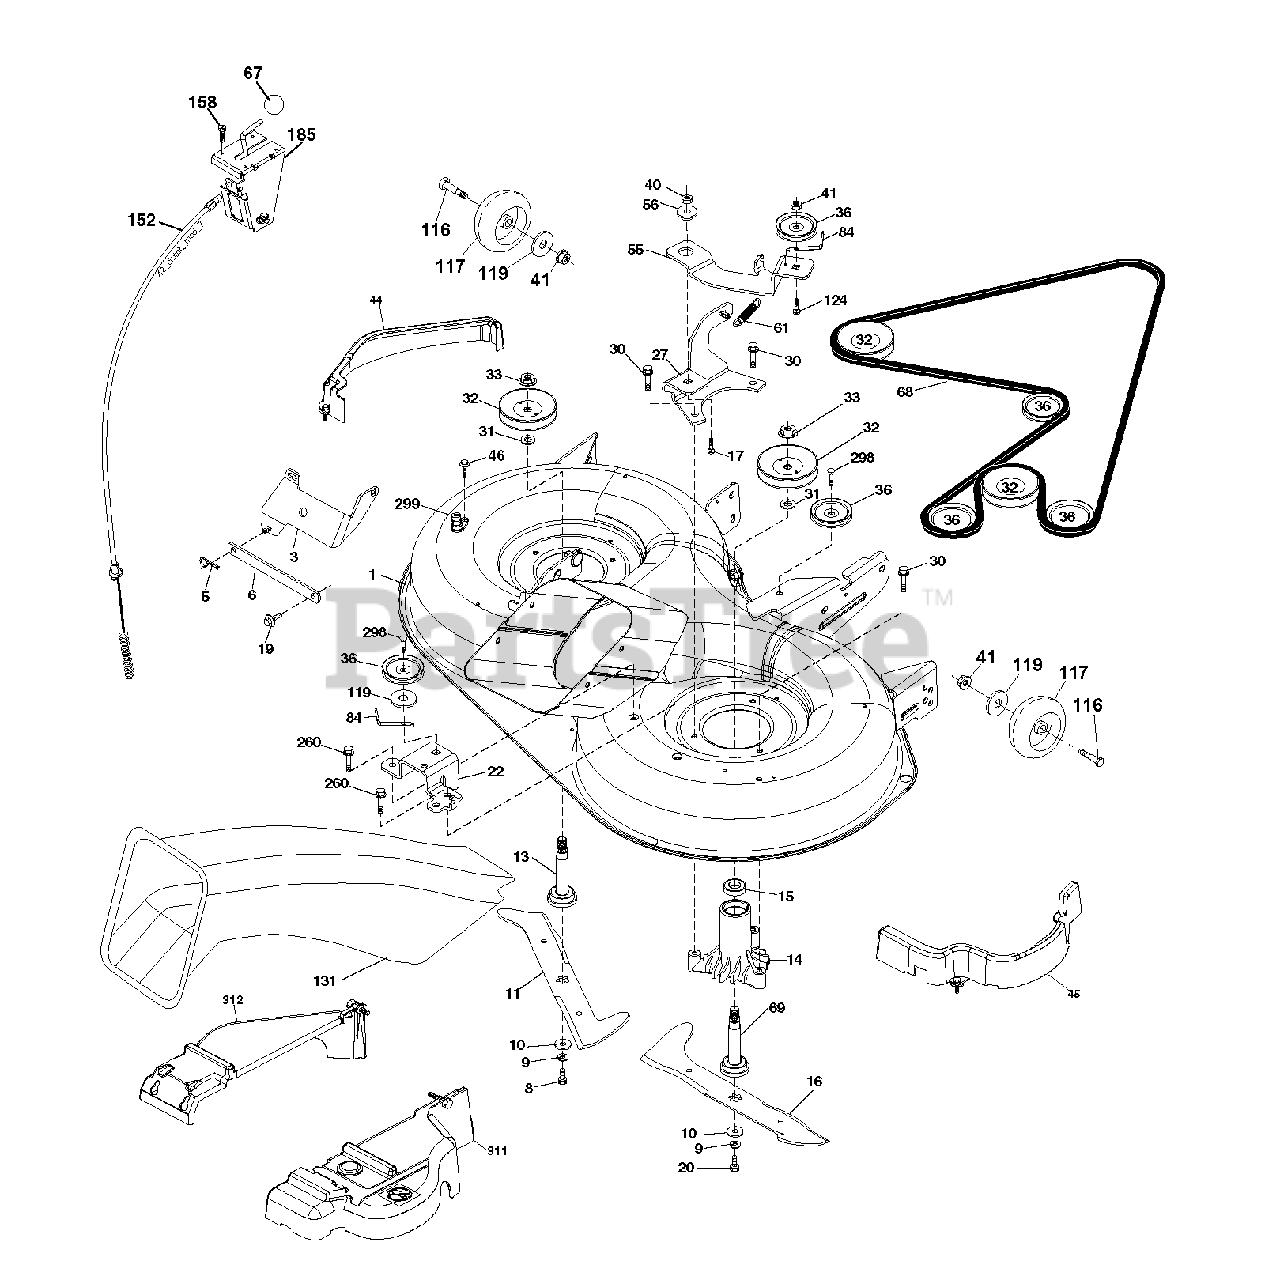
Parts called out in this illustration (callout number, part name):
3	BRACKET.ASM.BAR.SWAY.CHASS
5	RETAINER-SPRNG RB
6	BAR SWAY
9	LOCKWASHER
10	WASHER.BLADE
11	BLADE.3N1.LH.CRD.97
13	SHAFT ASM VENT
14	HSG MANDREL
16	BLADE.3N1.RH.CRD.97
17	BOLT.3/8-14X1.25
19	BOLT SHD 5/16-18
22	BRACKET.SUPT.IDLER.REAR.RH
27	BRACKET.ASM.SUSP.REAR.RH.
30	SCREW, WASHER HEAD
31	WASHER.SPACER.MANDREL
32	PULLEY MANDREL
33	NUT.FLANGE.LOCK.TOP
36	PULLEY.IDLER.4.25
40	LOCKNUT
41	NUT LOCK FLG 3/8-16 UNC
46	SCREW.1/4-20X5/8
56	SPACER.RETAINER.MOWER
67	KNOB T (3/8 HOLE)
68	BELT.DRIVE.CRD.97.2010
69	SHAFT.ASM.W/LWR.BRG.RH.THREAD
84	KEEPER, BELT IDLER
116	BOLT.SHOULDER.3/8-16X3-5/8
117	WHEEL. GUAGE RALLY
124	BOLT.3/8-16X1.50
131	CHUTE BAGGER
158	SCREW
185	HEAD ASM. CABLE CLUTCH
260	SCREW 3/8-16X1/2
298	SCREW LT
299	PORT.WASHOUT
